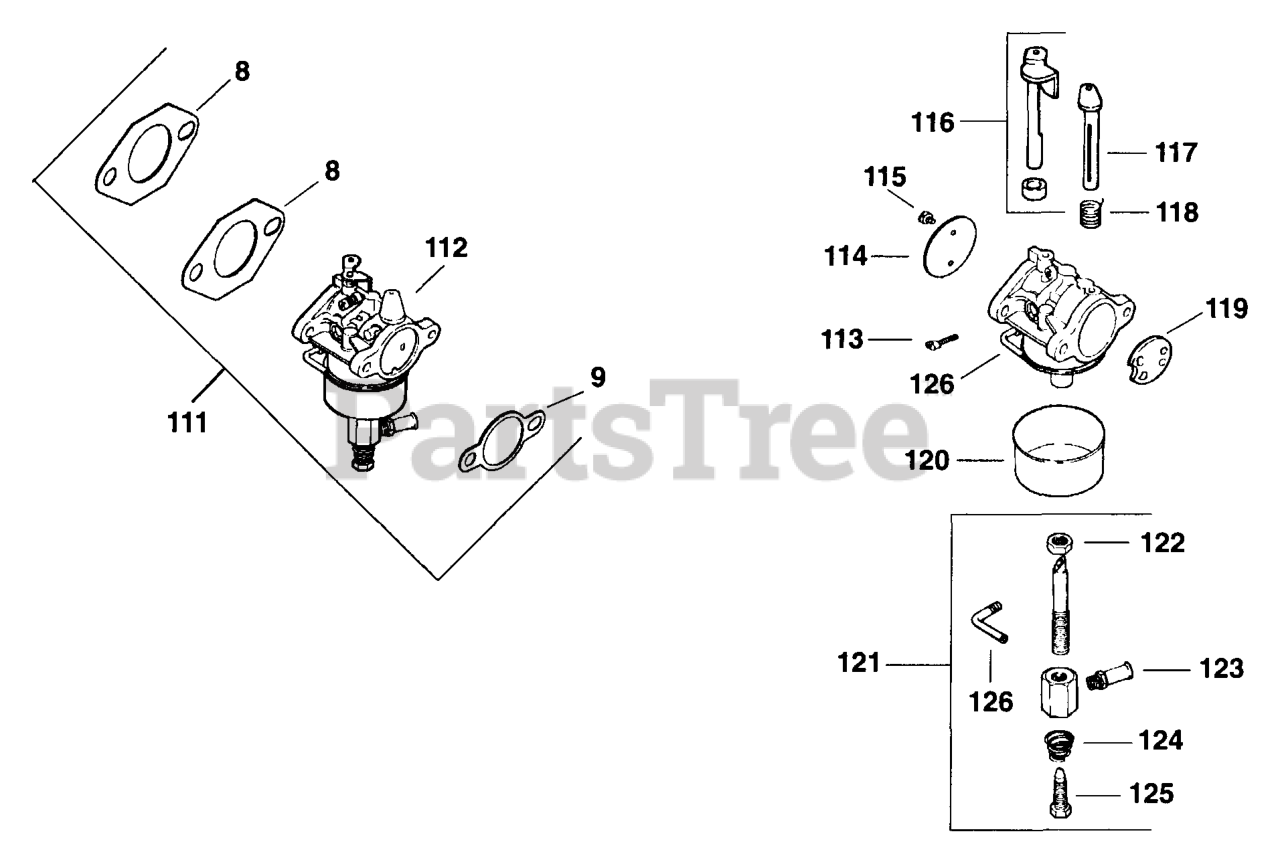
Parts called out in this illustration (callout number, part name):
8	GASKET, CARBURETOR
9	GASKET, AIR CLEANER BASE
111	CARBURETOR - USE 12 853 25
112	Carburetor assembly
115	SCREW - DISCONTINUED
115	SCREW, VALVE
116	SHAFT, THROTTLE
119	PLATE, CHOKE - DISCONTINUED
121	KIT, CARBURETOR REPAIR
122	NUT, 3/8-24 JAM, GRADE 2 - DISC.
123	FITTING, HOSE TO PIPE
124	SPRING, IDLE ADJUSTMENT - DISCONTINUED
125	SCREW, POWER ADJUSTMENT
126	TUBE, VACUUM
